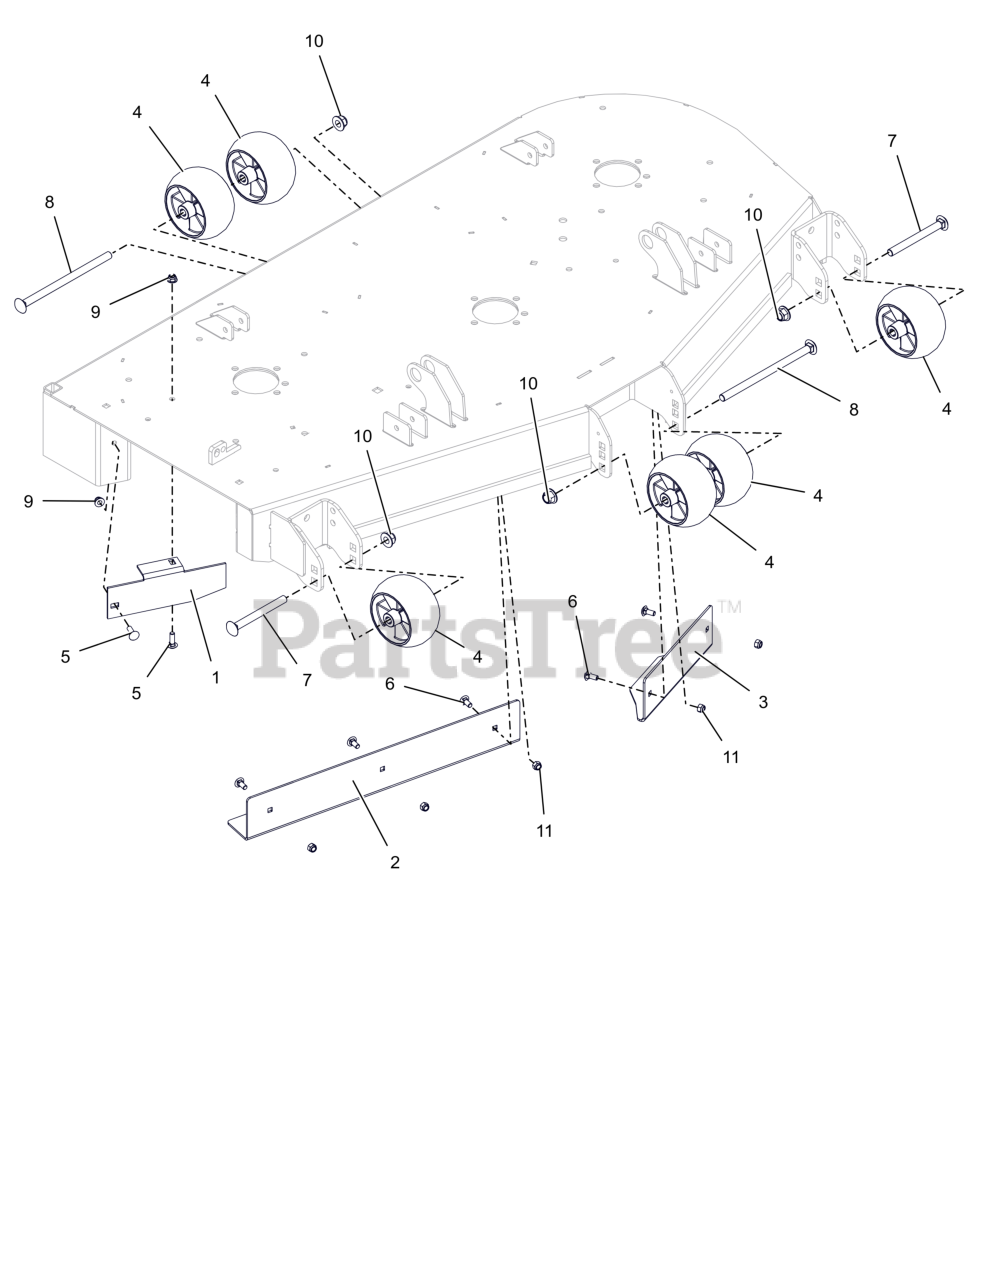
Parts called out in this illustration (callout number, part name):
1	BAFFLE, DISCHARGE, 52"
2	BAFFLE, 52" RH VACUUM (ORANGE)
3	BAFFLE, 52" LH VACUUM (ORANGE)
4	WHEEL, ANTI SCALP - 5X3 CTR W/RIBS
5	BLT,RHSN .31-18X1.00 G5 ZCC
6	BLT,RHSN .31-18X.75 G5 ZCC
7	BLT, RHSN .50-13X5.00 G5 ZCC
8	BTL,RHSN .500-13 X 8.5S G5 ZCC
9	NUT,LK-NYL-FLG .31-18 G5ZC120
10	NUT,NYL-FLG .50-13 GF ZCC
11	NUT,NYL .31-18 G5 ZCC
